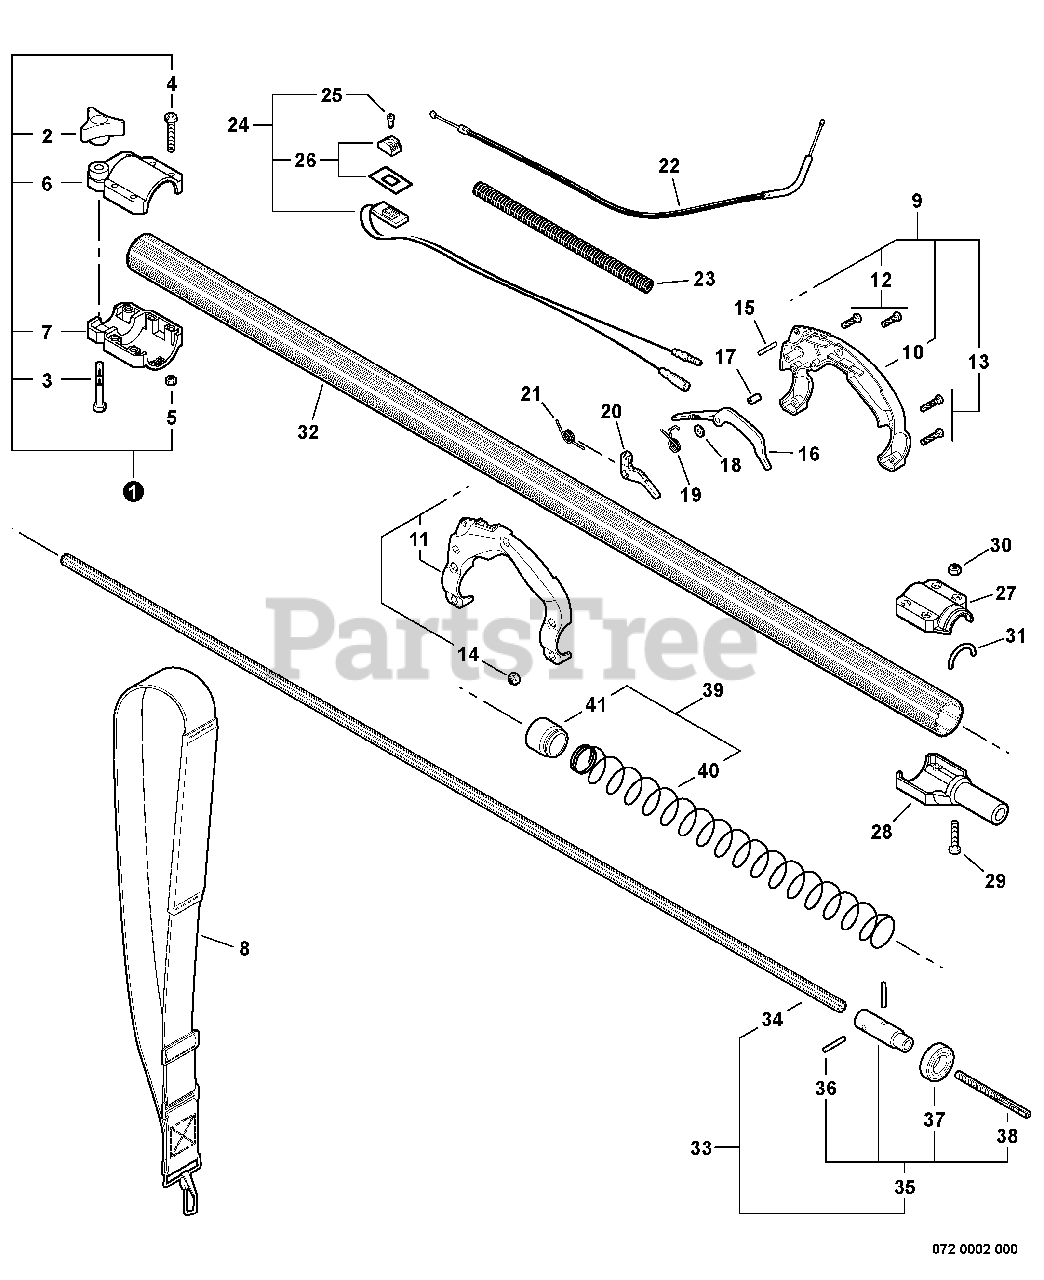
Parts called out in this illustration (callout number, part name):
1	CLAMP ASSY
2	THUMBSCREW
4	SCREW, TORX 10-24 UNC 1-1/4
5	NUT, LOCK 10-24 UNC
6	COLLAR, UPPER
7	COLLAR, LOWER
8	STRAP ASSY, SHOULDER
9	HANDLE SET, REAR
10	HANDLE, LEFT REAR
11	HANDLE, RIGHT REAR
12	SCREW, TORX 10-24 UNC 1-1/4
13	SCREW, TORX 10-24×1.5
14	NUT, LOCK 10-24 UNC
15	PIN, LOCATING 0.17 OD×0.75 L
16	LOCKOUT, THROTTLE
17	COLLAR 5.08×14.5
18	WASHER 5.5×12×0.8
19	SPRING, TORSION Ø0.39 I.D.
20	TRIGGER, THROTTLE
21	SPRING, TORSION
22	CABLE, THROTTLE
23	TUBE, FLEXIBLE
24	SWITCH, ON-OFF
25	SCREW 3×10
26	KNOB, SWITCH - ORANGE
27	CAP, MAIN PIPE
28	ADAPTER, LOWER DRIVE SHAFT
29	SCREW, TORX 10-24×1.5
30	NUT, LOCK 10-24 UNC
32	PIPE, MAIN
33	SHAFT ASSY, DRIVE
34	DRIVESHAFT
35	CONNECTOR, DRIVE SHAFT
37	BEARING, BALL 6002 DDU
39	BUSHING ASSY, FLOATING
40	SPRING, COMPRESSION
41	BUSHING, FLOATING
